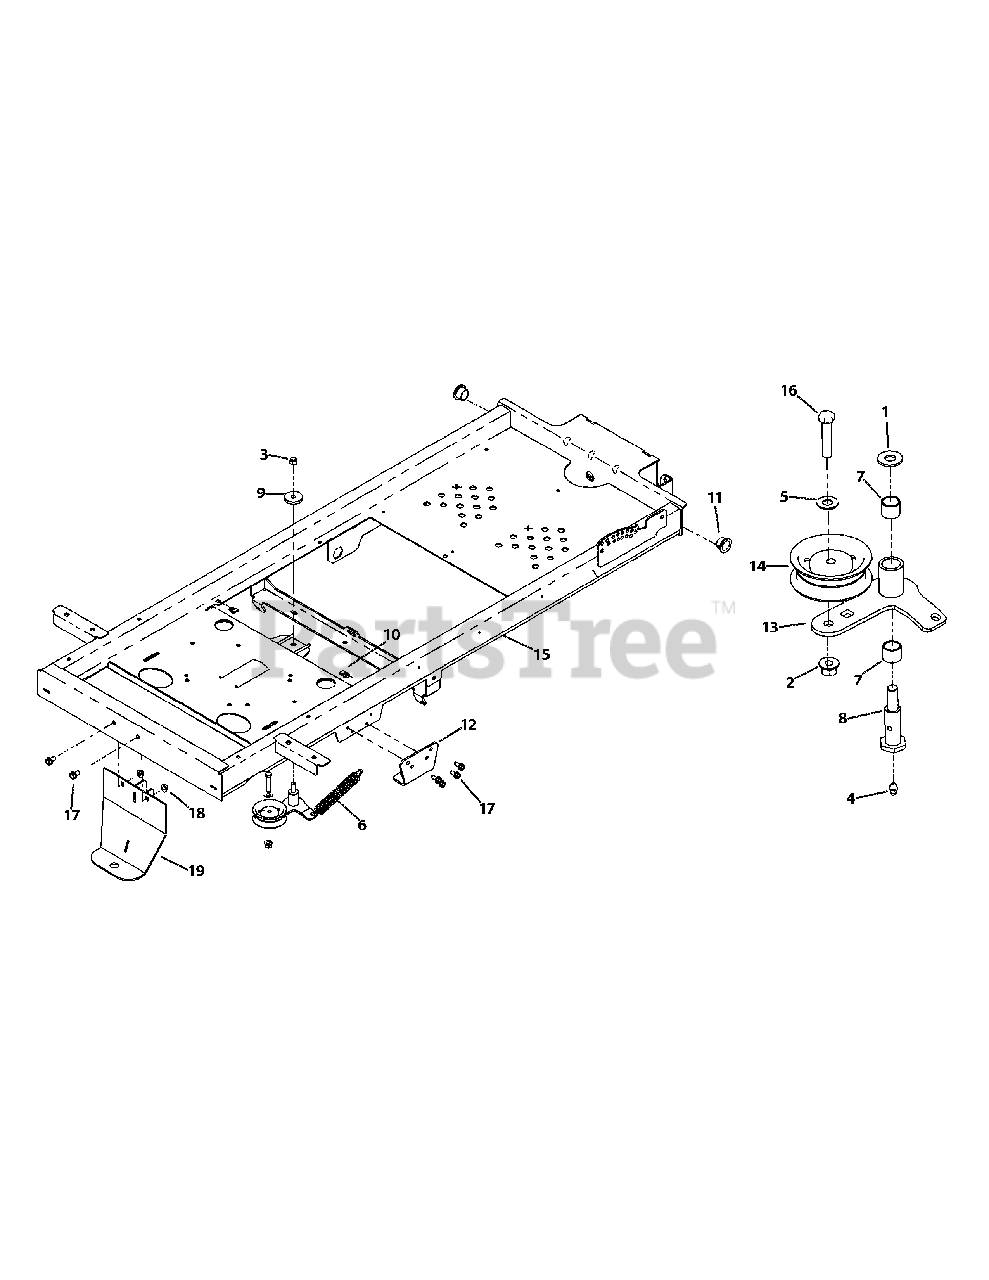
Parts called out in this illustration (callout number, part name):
1	Flat Washer, 3/8
2	Flange Lock Nut, 3/8-16
3	Nylock Nut, 7/16-14
4	Grease Fitting, 1/4-28 x 3/16
5	Washer, 3/8
6	Extension Spring, 1.00 x 5.00
7	Bearing Sleeve
8	Shoulder Bolt
9	Flat Washer, 7/16 x 1.75
10	U-Nut, 1/4-20
11	Bronze Bushing, 1.00 ID x 1.50 OD
12	Transmission Mounting Bracket
13	Idler Arm Assembly
14	Flat Idler Pully
15	Frame Assembly
16	Hex Cap Screw, 3/8-16 x 1-3.4
17	Self Tapping Screw, 5/16-18 x .750
18	Hex Flange Lock Nut, 5/16-18
